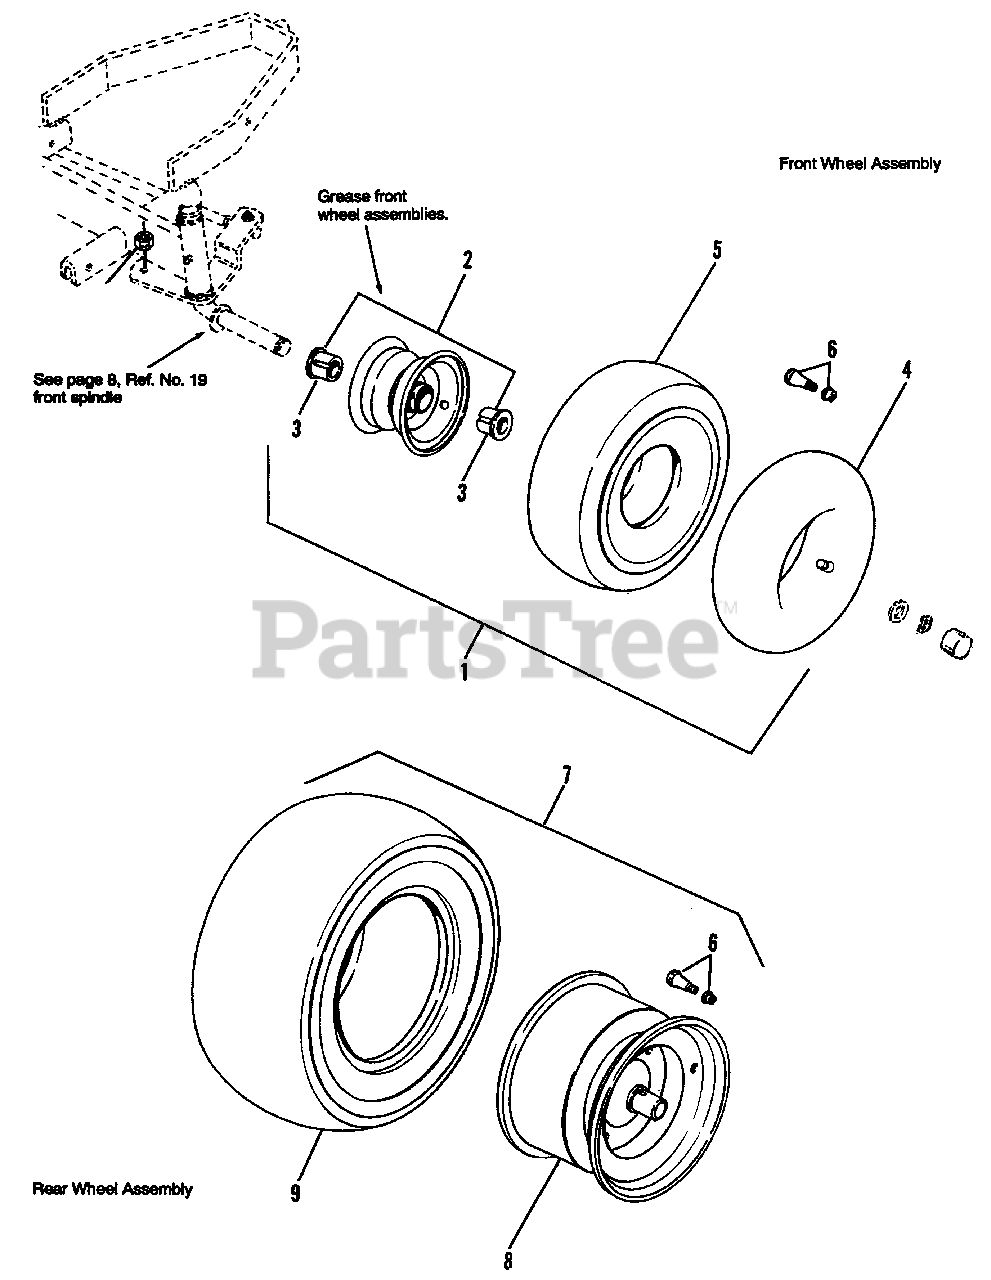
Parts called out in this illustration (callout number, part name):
1	FRONT WHEEL & TIRE ASSY., Beige, 15 x 6.00-6 (Incl. Ref. Nos. 2, 3, 4, 5 & 6)
1	FRONT WHEEL & TIRE ASSY., Silver, 15 x 6.00-6 (Incl. Ref. Nos. 2, 3, 4, 5 & 6)
2	FRONT WHEEL ASSY., Beige, (Incl. Ref. No. 3)
3	BEARING
4	TUBE, Front Wheel, 4.10/3.50-6
5	TIRE, Front Wheel, 15 x 6.00-6
6	VALVE STEM & CAP
7	REAR WHEEL & TIRE ASSY., Beige, 18 x 8.50-8 (Incl. Ref. Nos. 6, 8, 9 & 10)
8	REAR WHEEL ASSY., Beige, 18 x 8.50-8
9	TIRE, Rear Wheel, 18 X 8.50-8
